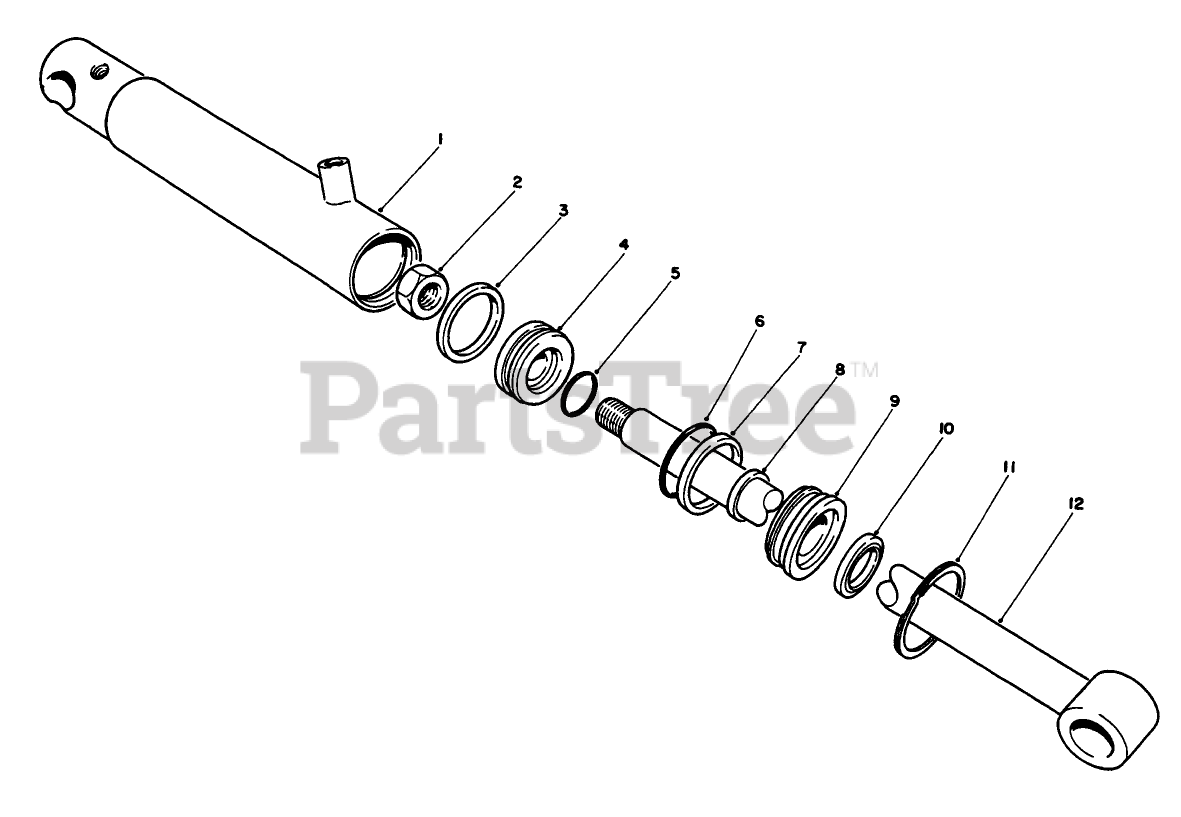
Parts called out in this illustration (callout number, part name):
1	Assembly-Tube
2	LOCKNUT
4	PISTON
6	O-Ring, Head
8	Poly-Pack
11	RING-RETAINING
12	SHAFT W/CLEVIS
